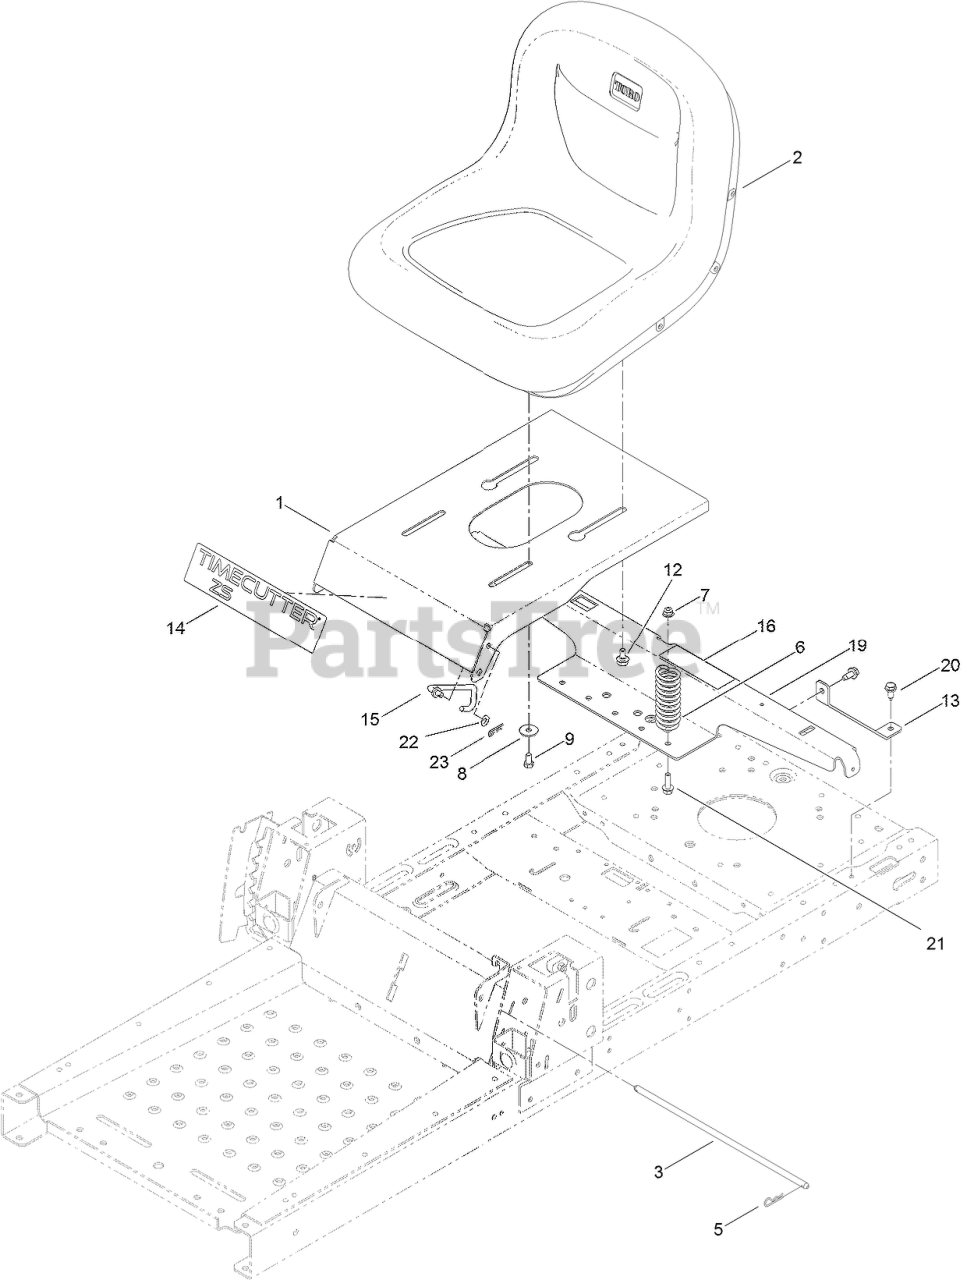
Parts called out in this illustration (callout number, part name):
1	PAN-SEAT
2	SEAT-15 INCH
3	ROD-PIVOT, NARROW
5	PIN-COTTER
6	SPRING-COMPRESSION
7	NUT-HF, NI
8	WASHER-PIVOT
9	SCREW-HH
12	BOLT-SHOULDER
13	SUPPORT-TANK, REAR
14	DECAL-TIMECUTTER
15	STOP-SEAT
16	DECAL-SERVICE, CE
19	SUPPORT-POD
20	SCREW-HWHTF
21	SCREW-HHF
22	WASHER-PLAIN
23	PIN-COTTER
